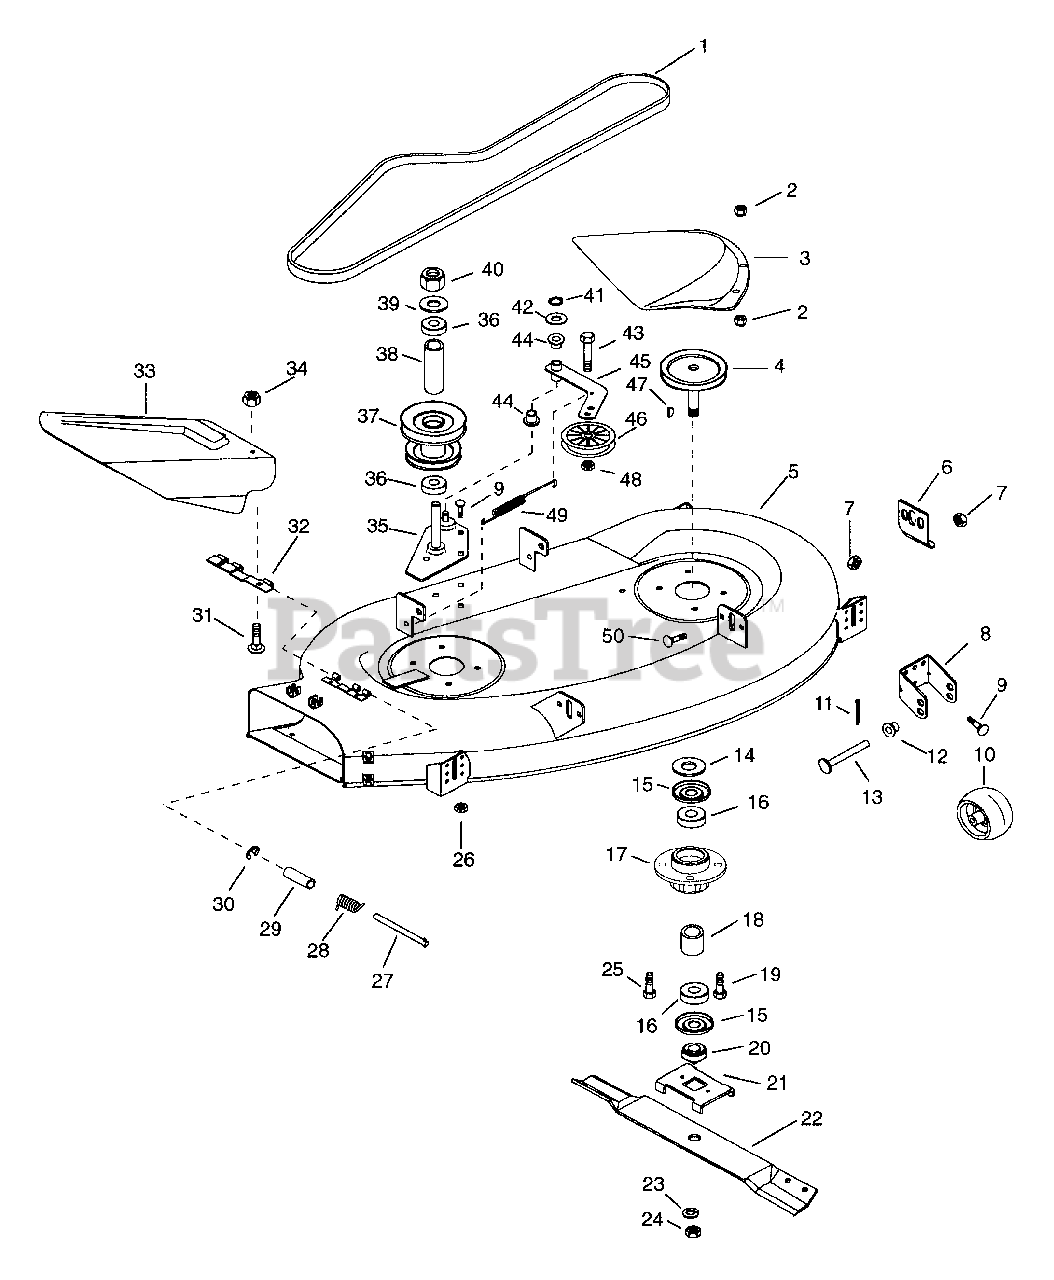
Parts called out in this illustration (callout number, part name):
1	V-BELT, 4L-WRAPPED
2	NUT-LK-CTR .375-16 GR A PL
4	L. SPINDLE SHEAVE
4	R. SPINDLE SHEAVE
5	40" MOWER DECK W/DECALS
5	40" MOWER DECK ASSY COMPLETE
6	MOWER ADJUSTMENT TAB
7	NUT-FLG. .312-18 PL
8	ROLLER CLEVIS
9	BLT-RDHDSQNK .312-18X.62SHTPL
11	PIN-COTR .15 X 1.0 PL
12	BSHG-FLG .372X.500X.312X.625NY
13	PIN-CLEV .371X3.25 YWZC
14	WSHR-FL-STL .755X1.250X.125
15	BEARING SLINGER
16	BRG-BALL .750X1.781X.61
17	SPINDLE HOUSING
18	SPACER .753X1.000X1.140
19	BLT-RDHDSQNK .38-16X1.0 PL
20	RETAINER HUB
21	BLADE TRAY 48
23	WSHR-LK .750X.188 MED PL
24	NUT-JAM .75-10 PL
25	BLT-HEX .38-16X1.00 PL GR5
26	NUT-FLG. .312-18 PL
28	SG-TORS .095X.50X 1.0
29	BSHG-SLV .334 X .502 X 1.437
30	RG-RTNG-EXT .312X.025
31	BLT-RDHDSQNK .25-20X.50 SHT PL
32	HINGE PLATE
33	40IN. CHUTE DEFLECTOR
34	NUT-LK-FLG .250-20 PL
35	MOUNT PLATE 40"
36	BRG-BALL .625X1.375X.44
37	JACKSHAFT PULLEY
38	SPACER .640X.880X2.545
39	WSHR-FL-STL .640X1.005X.062 PL
40	NUT-LK-NYL.625-18 PL
41	RG-RTNG-EXT .500X.042 (E)
42	WSHR-FL-STL .505X.880X.072 PL
43	BLT-HEX .38-16X1.50 PL GR5
44	BSHG-FLG .500X.625X.187X.750FD
45	IDLER ARM
46	IDLER-FLAT 3.00X.38
47	KEY-WDRF .188X.625X.31 SAE9MOD
48	NUT-LK TOP .375-16 GR C YWZC
49	SG-TENS .113X.812X7.00
50	BLT-RDHDSQNK.31-18X.75GR5SHTPL
